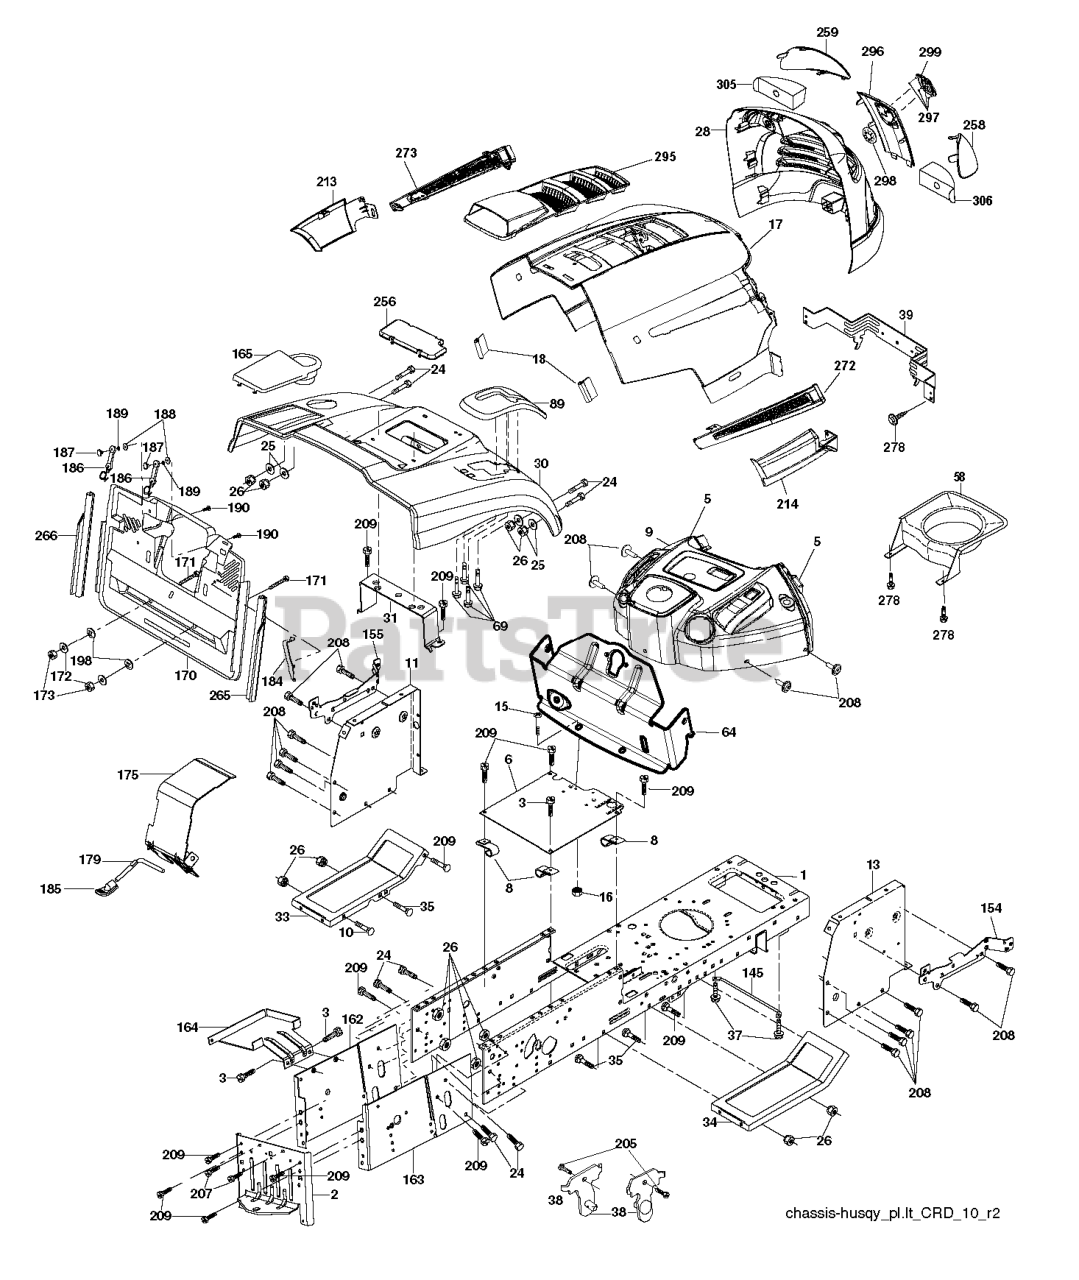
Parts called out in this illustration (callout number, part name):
2	DRAWBAR
3	SCREW 3/8-16X3/4
5	BUMPER DASH
6	PLATE
8	CLIP,INSULATOR
10	BOLT D
11	PANEL.DASH.LH.LTX
13	PANEL ASM, DASH RH
15	Screw, Machine, Truss Head 5/16-18 UNC x 3/4
16	NUT
17	HOOD.HUSQVARNA.LT.ORANGE
18	BUMPER.HOOD.TEX.HUSQVARNA
25	WASHER
26	NUT
28	GRILLE.SVC.HUSQVARNA.GREY
30	FENDER.PNT.CRD.MS-668
31	BRACKET SUPPORT FENDER
33	FOOTREST PNT LH
34	FOOTREST PNT RH
37	Screw 5/16-18 x 1/2 Hex, Self Tapping 5/16-18 x 1/2
38	BRACKET ASM PIVOT MOWER REAR
39	BRACKET PIVOT
69	SCREW.HI-LO.CONSOLE
89	CONSOLE.CRD.AUTO.GREY.2005
145	ROD.PIVOT.HOOD
162	BRACKET
163	BRACKET EXTEN CHASSIS RH CRD
165	RP.COVER.BATTERY.CRD.GREY
172	WASHER
175	DOOR TRAP
179	ROD PIVOT FBI
184	BRACKET.ACTUATOR.BAGGER.SRD
185	KNOB.BRAKE.PARKING.ROD
186	LATCH ASSY
187	WELDNUT
189	LOCKWASHER #10
190	SCREW
207	SCREW, 5/16-18 X 1/2
208	SCREW 3/8-16X1/2
209	SCREW, 3/8-16X3/4
213	SKIRT SIDE LH
214	SKIRT SIDE RH
256	COVER FENDER CRD
258	LENS.HUSQVARNA LT.RH
259	LENS.HUSQVARNA LT.LH
265	SEALING
266	SEALING
272	VENT SIDE HOOD LH
273	VENT SIDE HOOD RH
278	SCREW.#10 X 0.750.BOS
295	VENT TOP HOOD
296	TRIM
297	CLIP.RETAINER.TINNER.
298	NUT PUSH M
299	LOGO.HUSQ.GT.LT.CROWN.H
305	INSERT REFLECTIVE
306	INSERT.REFLECTIVE.RH.
